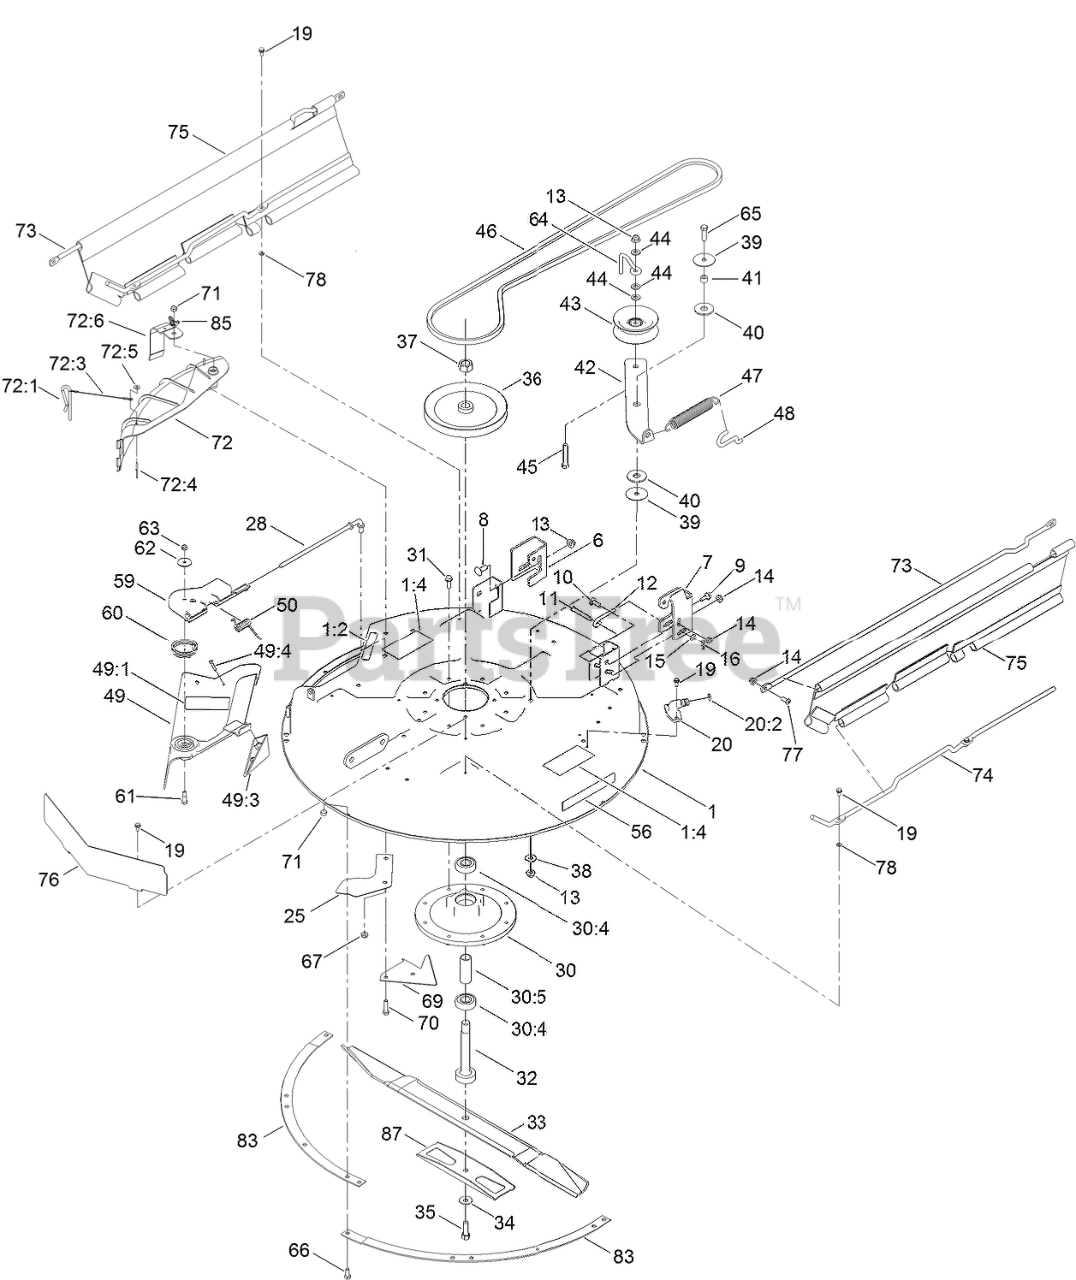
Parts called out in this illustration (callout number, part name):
1	32 INCH DECK AND DECAL ASM
1:2	DECAL-DANGER
1:4	DECAL-DANGER, DECK
6	Bracket-Hanger, RIGHT REAR
7	Bracket-Hanger, LEFT REAR
10	SCREW-CARR
11	Pin-Clevis
13	NUT-HF, NI
14	NUT-HF
15	WASHER-PLAIN
16	PIN-HAIR
19	SCREW-HWH
20	FITTING-WASHOUT
20:2	O-RING
25	RAMP-DEFLECTOR
28	ROD-PIVOT
30	SPINDLE HOUSING ASM
30:4	BEARING-BALL
30:5	SPACER-BEARING
31	SCREW-TAPTITE
32	SHAFT-SPINDLE
33	BLADE-RECYCLER, 31.35 INCH
34	WASHER-BELLEVILLE
35	SCREW-HH
36	PULLEY - 32" DECK
37	NUT-HEX
38	WASHER-HARDENED
39	Washer
40	WASHER-FRICTION, COMPOSITE
41	SPACER
42	PLATE-IDLER, PIVOT
43	PULLEY-IDLER, FLAT
44	WASHER-FLAT
45	SCREW-HH
46	V-BELT
47	SPRING-EXTENSION
48	HOOK-RETURN SPRING
49	32 INCH DEFLECTOR ASM
49:1	DECAL-DANGER
49:3	KICKER
49:4	SCREW-PPH
50	SPRING-DEFLECTOR
56	DECAL-RECYCLER
59	PIVOT-HINGE, DEFLECTOR
60	SPRING-TORSION
61	BOLT-SHOULDER
62	WASHER-FLAT
63	NUT-HEX
64	BELT GUIDE - IDLER
65	SCREW-HH
66	SCREW-HH
67	NUT-HEX
70	SCREW-HH
71	NUT-HEX
72	DISCHARGE COVER ASM
72:1	PIN-LOCKING, CHUTE
72:3	LANYARD
72:4	RIVET-BLIND
72:5	WASHER-PLAIN
73	ROD SUPPORT, UPPER
74	ROD-SUPPORT, LOWER
75	GUARD-SIDE
76	SHIELD-FRONT
77	SCREW-HSBH
78	NUT-RETAINING
83	RING-DECK
85	NUT WING
87	STIFFENER
